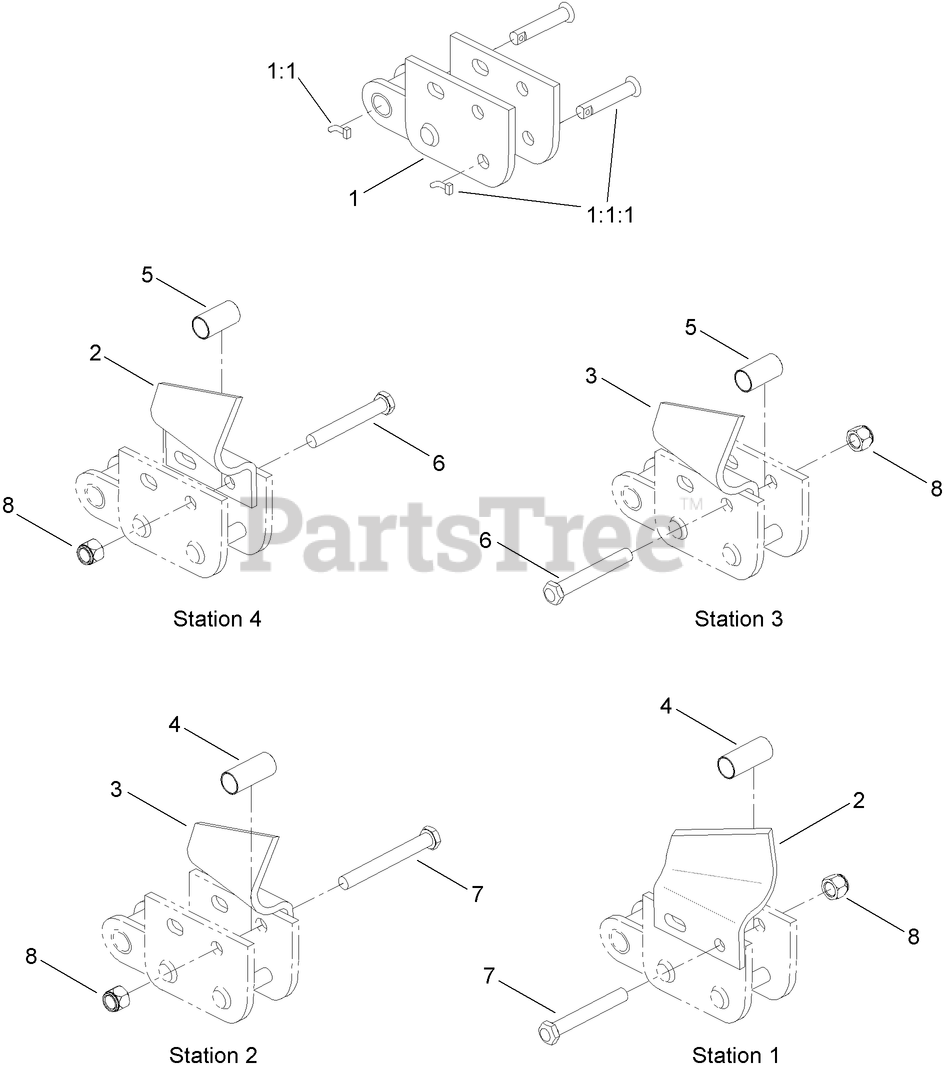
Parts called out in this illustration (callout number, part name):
1	CHAIN REPAIR LINK ASM
1:1	NOTCHED PIN AND KEEPER ASM
1:1:1	PIN-KEEPER
2	CUTTER-CUP, LH
3	CUTTER-CUP, RH
4	SPACER-TUBE, OUTSIDE MOUNT
5	SPACER-TUBE, INSIDE CUP MOUNT
6	BOLT-HH
7	BOLT-HH
8	NUT-LOCK
